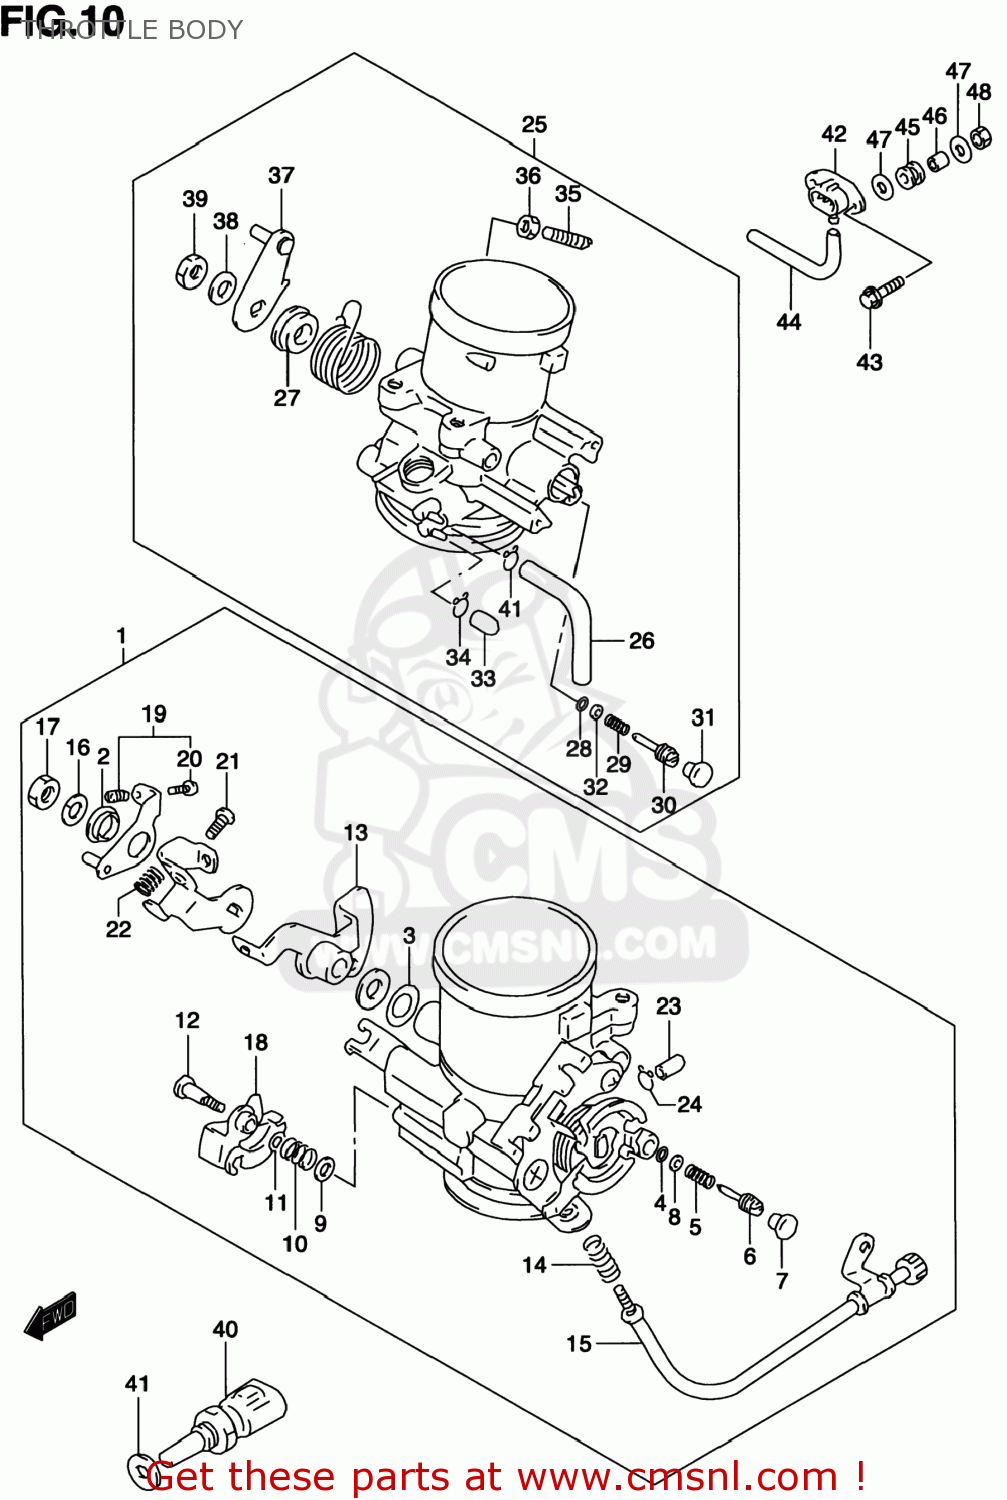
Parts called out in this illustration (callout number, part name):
1	BODY ASSY,THROTTLE FR
2	RING
3	PACKING (NAS)
4	O RING,PILOT AIR SCREW
5	SPRING
6	SCREW,AIR
7	PLUG
8	WASHER
9	WASHER
10	SPRING
11	RING
12	SCREW
13	LEVER ASSY
14	SPRING
15	ADJUSTER ASSY
16	WASHER
17	NUT
18	LEVER ASSEMBLY
19	SCREW SET,ADJUST
20	SCREW
21	SCREW
22	SPRING
23	CAP
24	CLIP
25	BODY ASSY,THROTTLE RR
26	HOSE
27	RING
28	O RING,PILOT AIR SCREW
29	SPRING
30	SCREW,AIR
31	PLUG
32	WASHER
33	CAP
34	CLIP
35	SCREW
36	NUT
37	LEVER ASSY
38	WASHER
39	NUT
40	SENSOR,WATER TEMP
41	GASKET(12X17X1) (NAS)
42	SENSOR,MAP
43	BOLT
44	HOSE(4X8X600)
45	CUSHION
46	SPACER(6.5X10X10)
47	WASHER(6.5X20X1.2)
48	NUT
